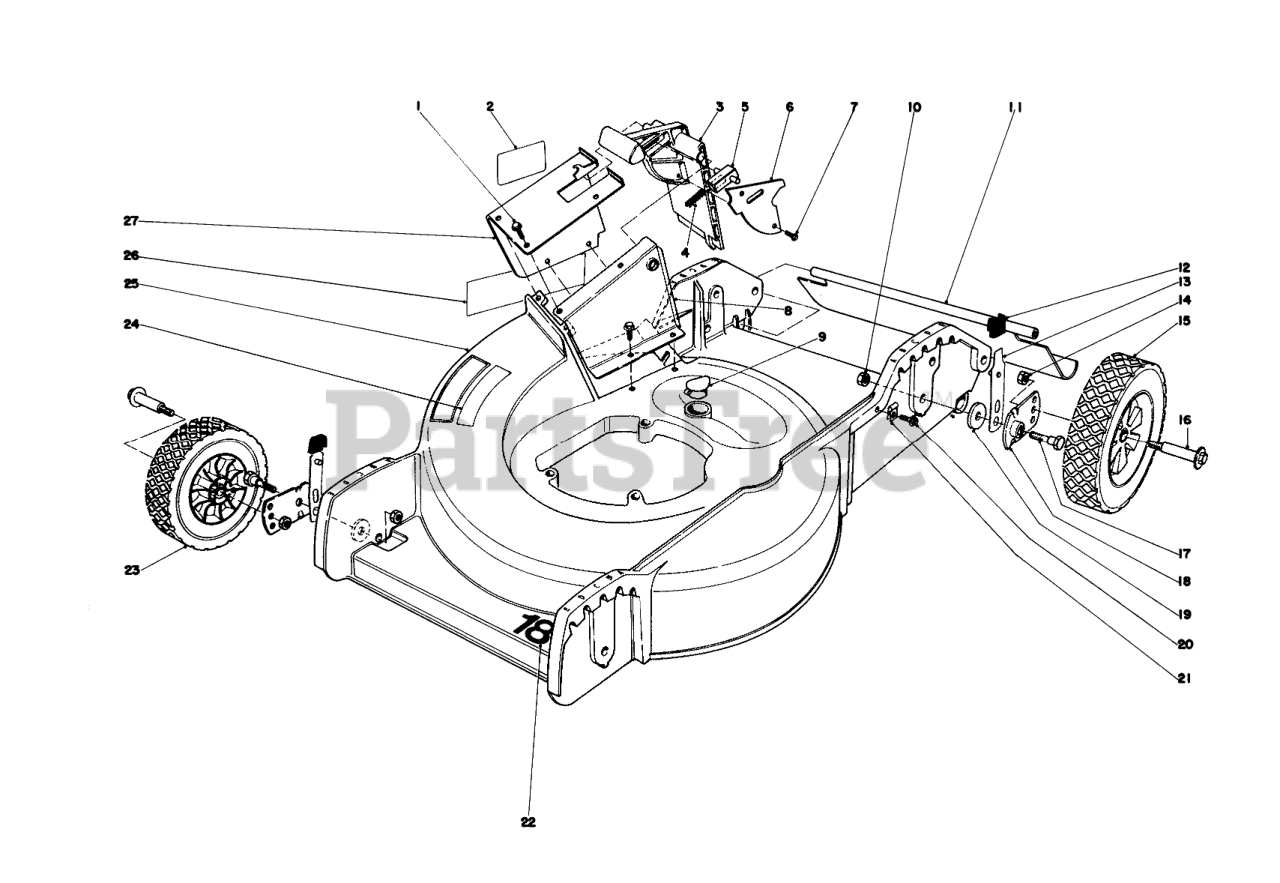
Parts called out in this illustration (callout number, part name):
1	SCREW
2	Decal Door
3	Door Mulching
4	SPRING-COMPRESSION, LATCH
5	Door Latch
6	Cover Door
8	Inner Tunnel
9	WASHOUT PLUG
10	Nut
11	SHIELD - TRAILING
12	KNOB-ARM
13	SPRING ARM ASM
14	Nut
15	WHEEL TIRE ASM 8 IN
16	BOLT-WHEEL
17	PIVOT SCREW
18	PIVOT ARM ASSY
19	PIVOT WASHER
20	SCREW-HWHTF
21	Clamp
22	Decal
23	WHEEL TIRE ASM 7 IN
24	Decal Place Foot Here
25	Housing
26	Decal Door
27	Tunnel Outer
